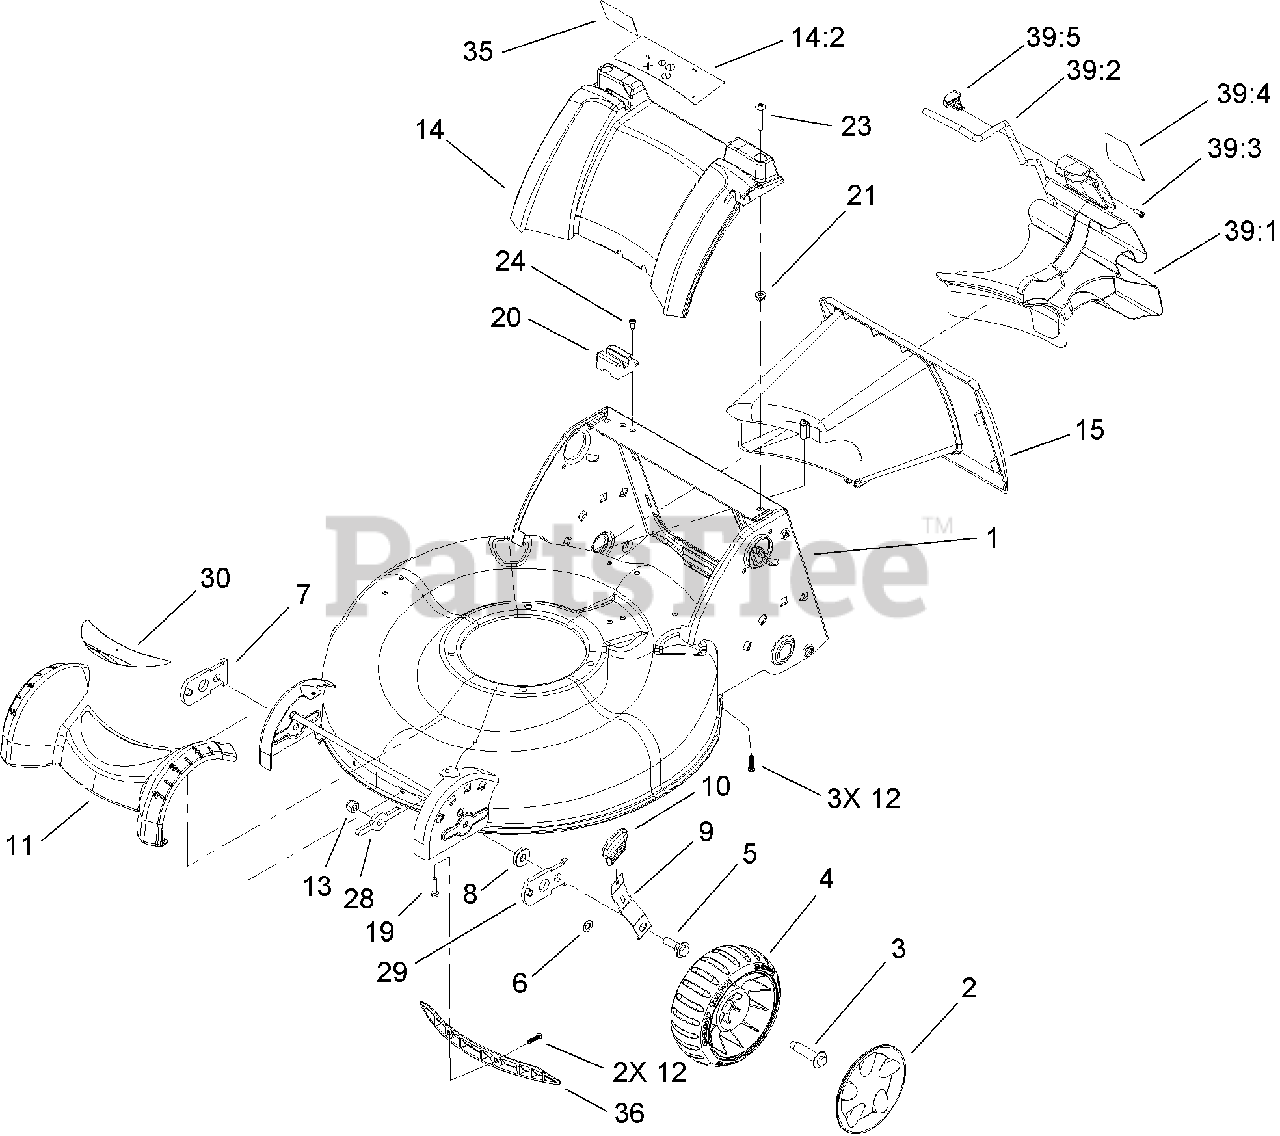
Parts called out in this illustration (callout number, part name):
1	HOUSING ASM
2	COVER-WHEEL, 7 INCH
3	BOLT-SHOULDER
4	7 INCH WHEEL ASM
5	BOLT-SHOULDER
7	ARM-PIVOT, RH
9	ARM-SPRING
10	KNOB-LEVER, HOC
11	COVER-FRONT
12	SCREW-PLASTITE
13	NUT-LOCK, NI
14	COVER-REAR
14:2	DECAL-SAFETY
15	TUNNEL
19	SCREW-PLASTITE
20	MODULE-SWITCH
21	NUT-CLIP
23	SCREW-PTH
24	SCREW-THREAD FORMING
28	WASHER-SUPPORT, FRONT
29	ARM-PIVOT, LH
35	DECAL-BAG ATTACHMENT
36	INSERT-HOUSING
39:1	PLUG-CHUTE
39:2	LATCH-PLUG
39:3	SCREW-PPH
39:5	RETAINER-LATCH
